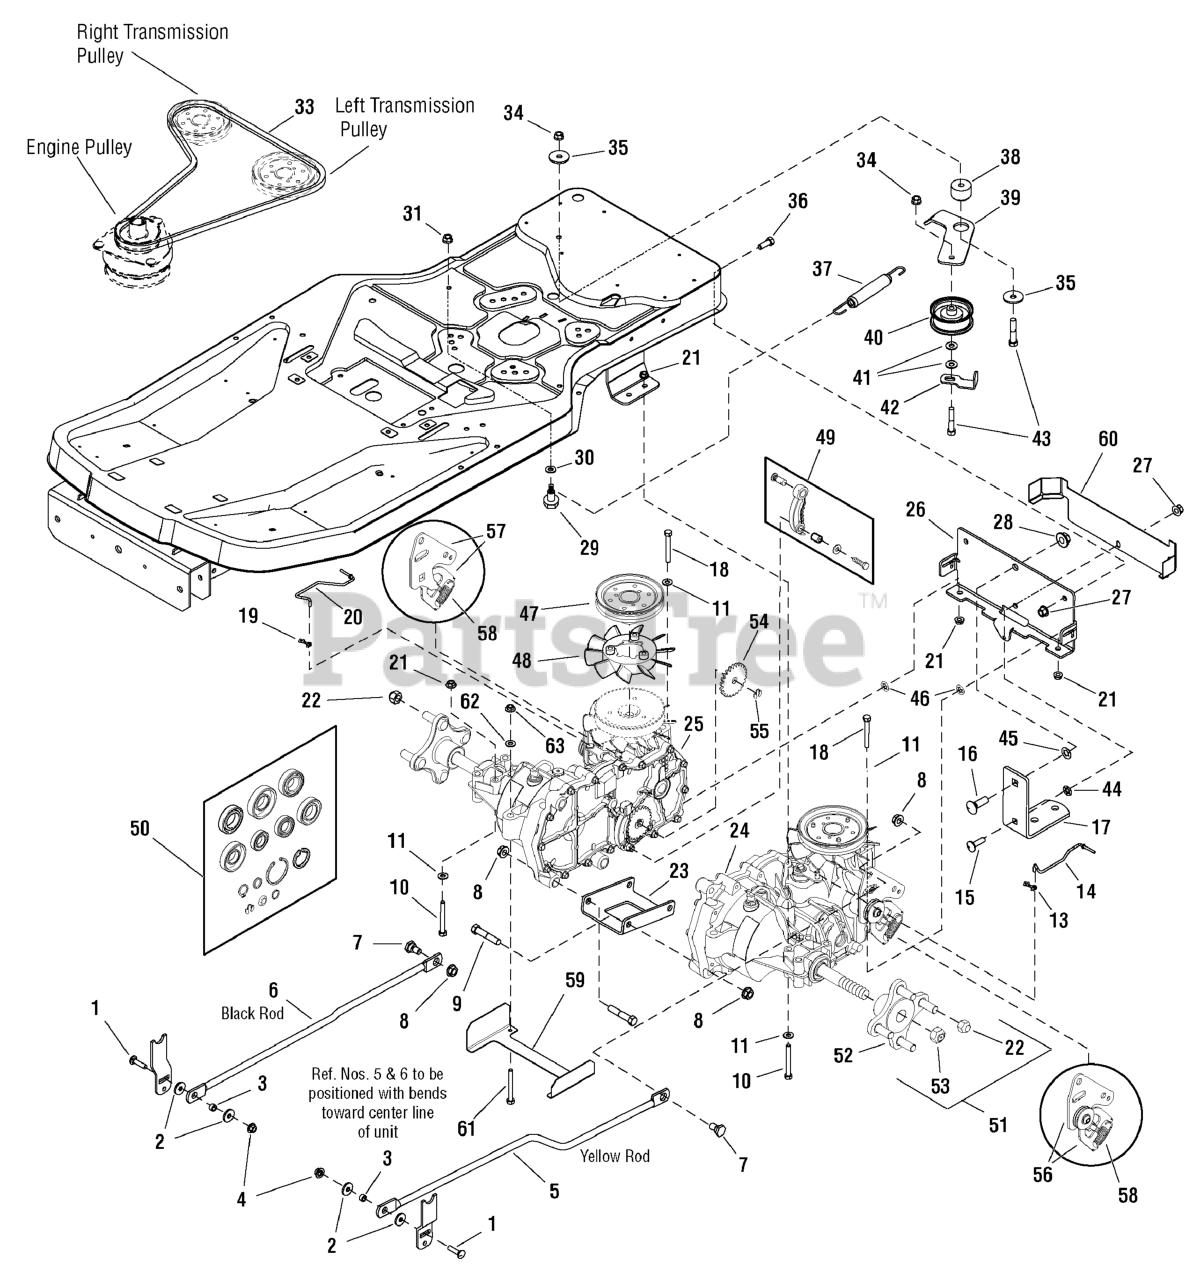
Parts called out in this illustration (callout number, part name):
1	BOLT, Carriage, 5/16-18 x 1 1/4
2	WASHER, .34 ID x 1 OD x .13 THK
4	NUT, Hex Keps, 5/16-18
5	ROD, Control L.H.
6	ROD, Control R.H.
7	BOLT, Shoulder
8	NUT, Hex Flange Two-Way Lock, 7/16-14
9	CAPSCREW, Hex Head, 7/16-14 x 2-1/4, G8
10	CAPSCREW, Hex Head, 5/16-18 x 2-3/4, G5
11	WASHER, 5/16
13	CLIP, Rod End Linkage
14	ROD, Tow Valve L.H.
15	BOLT, Carriage, 3/8-16 x 1-1/4, G5
16	BOLT, Carriage, 1/2-13 x 1-1/2, G5
18	CAPSCREW, Hex Head, 5/16-18 x 2-1/2, G5
19	CLIP, Rod End Linkage
20	ROD, Tow Valve R.H.
21	NUT, Hex Flange Whiz Lock, 5/16-18
22	NUT, Wheel Hex, 1/2-20
23	SUPPORT, Transmission Center
24	TRANSMISSION, Hydro Gear EZT L.H.
25	TRANSMISSION, Hydro Gear EZT R.H.
26	SUPPORT, Transmission Rear
27	NUT, Hex Flange, 3/8-16 ESNA
28	NUT, Hex Flange, 1/2-13
29	BOLT, Shoulder, 5/16-18 x 1-5/8
30	WASHER, .34 ID x .87 OD x .06 THK
31	NUT, Hex Flange, 5/16-18
33	V-BELT, Transmission Drive, 54.4
34	NUT, Hex Flange Two-Way Lock, 3/8-16
35	WASHER, .41 ID x 1-1/2 OD x .12 THK
36	CAPSCREW, Hex Head, 3/8-16 x 1, G5
37	SPRING, Extension
38	SPACER, Powdered Metal
39	ARM, Idler
40	PULLEY, Idler Flat
41	WASHER, .41 ID x .87 OD x .08 THK
42	BELT GUIDE
43	CAPSCREW, Hex Head, 3/8-16 x 2, G5
44	NUT, Push Pal, 3/8
45	NUT, Push Pal, 1/2
46	NUT, Push Pal, 5/16
47	PULLEY, 4-1/2" Transmission
48	FAN, 6" Transmission
49	PARKING BRAKE ARM ASSEMBLY, Transmission
50	HYDRO SEAL KIT
51	HUB REPLACEMENT KIT
52	HUB, EZT Transmission
53	NUT, EZT Transmission
54	GEAR, Parking Brake, Transmission
55	CLIP, E Transmission Parking Brake
56	ARM, Control Kit L.H.
57	ARM, Control Kit R.H.
58	SPRING, Extension
59	BRACKET, Clutch Guard
60	BRACKET, Rear Fan
61	CAPSCREW, Hex Head, 5/16-18 x 2-1/4
62	WASHER, Flat, 3/4
63	NUT, Hex Flange, 5/16/18
